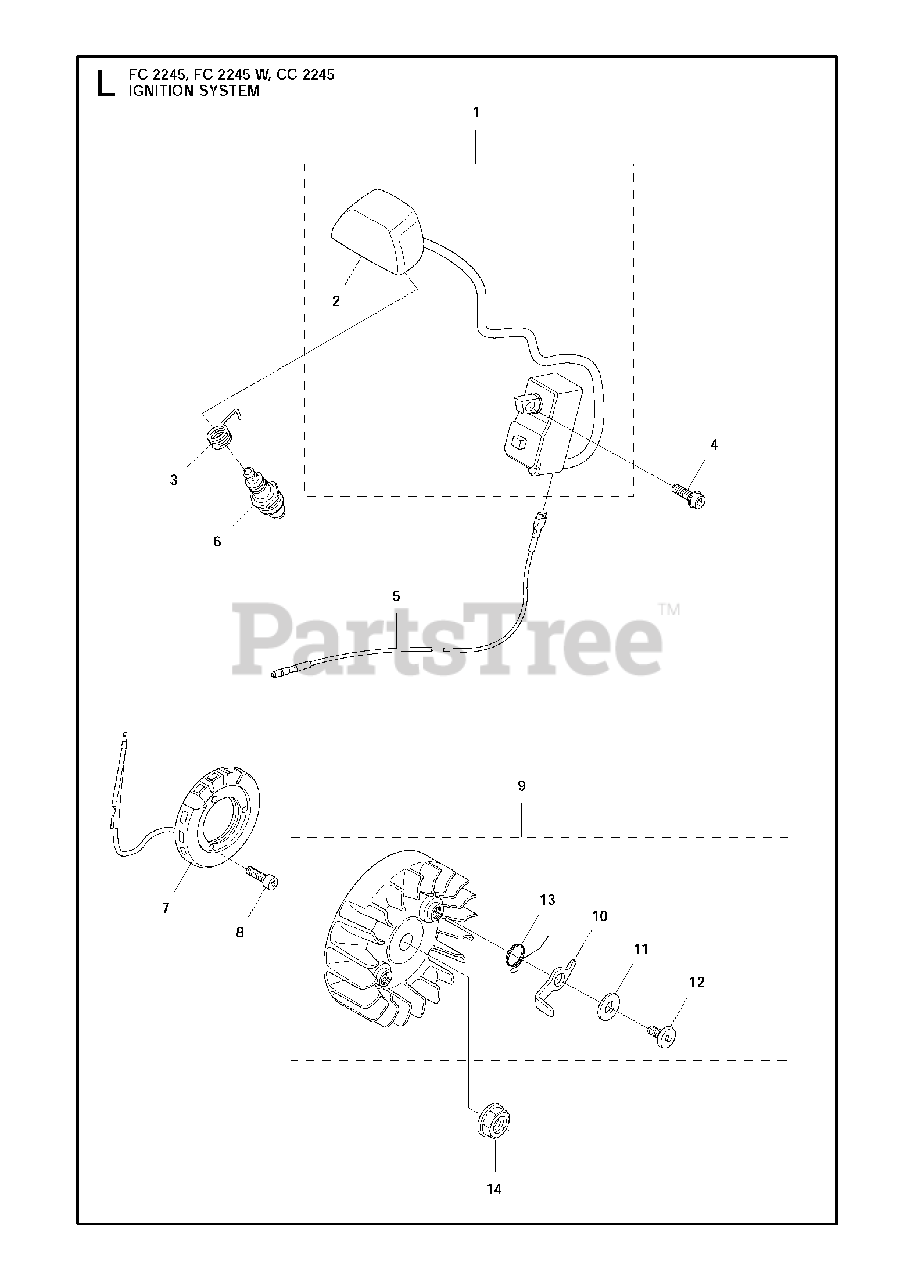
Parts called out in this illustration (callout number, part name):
1	IGNITION MODULE
1	RP IGNITION MODULE
2	CAP
3	SPRING
4	SCREW IHSCFM
5	SHORT CIRCUIT CABLE
6	CMR6H SPARK PLUG NGK
7	GENERATOR
10	STARTER PAWL
11	WASHER
12	PIN, STARTER CATCH
13	SPRING
14	NUT W/ WASHER
